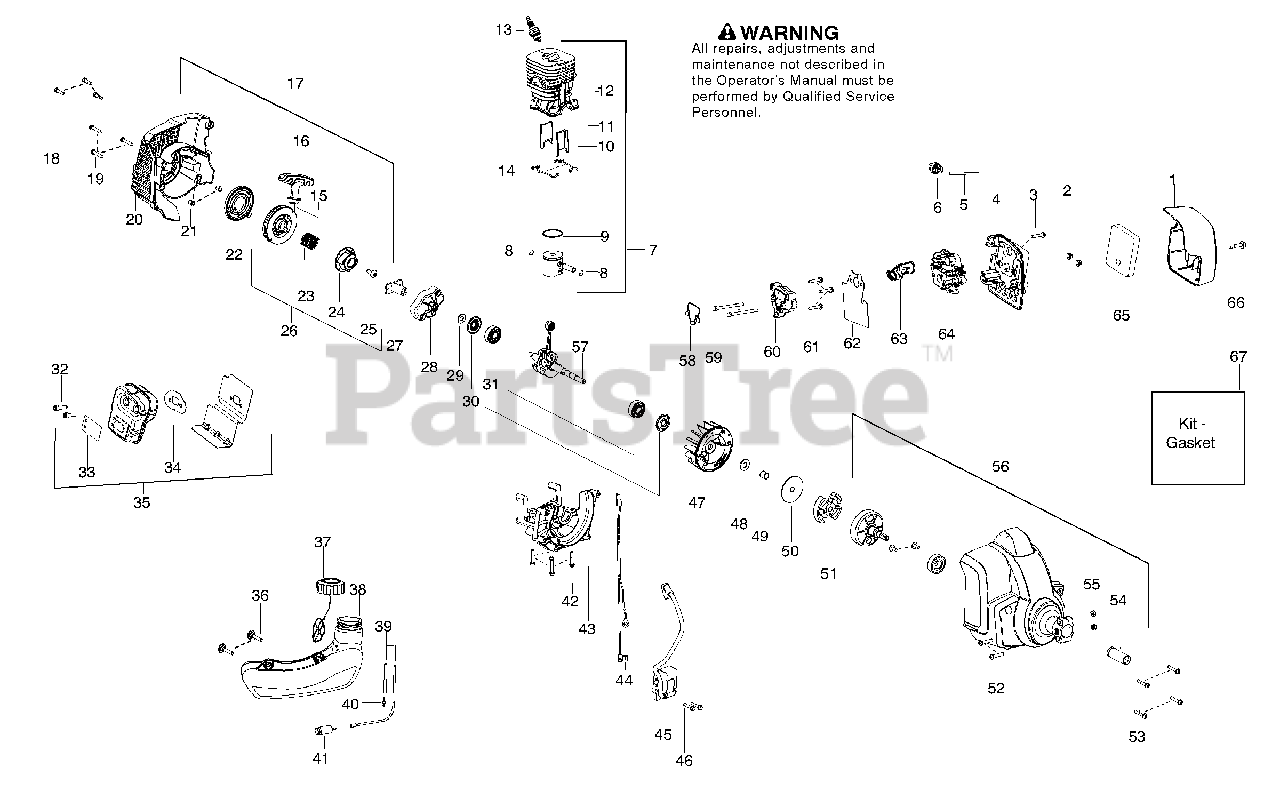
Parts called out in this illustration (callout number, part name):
1	Cover - Airbox
2	Nut - Carb. Screw
4	Base - Airbox
6	Assy - Purge Bulb
7	Kit - Piston/Cylinder
8	Retainer - Piston pin
9	Ring - Piston
10	Insert - Front Transfer Port
11	Insert - Rear Transfer Port
12	Cylinder - Machined
13	Spark Plug (RCJ- 6Y)
14	Seal - Cylinder (Kit)
16	Handle - Starter
17	Assy - Starter/Shroud
18	Screw M4 x 1.75
19	Screw m5x25mm
20	Assy - Starter Hsg. w/eyelet
22	Kit - Starter Spring
23	Spring - Starter Hub
24	Hub - Starter
26	Kit - Starter Pulley
27	Coupling - Starter
28	Assy - Starter Cup
29	Washer - Flat
30	Seal - Crankshaft (kit)
31	Bearing - Crankshaft
32	Bolt - Muffler
33	Kit - Spark Arrestor
34	Gasket - Muffler (kit)
35	Assy - Muffler
36	Screw - Tank Retainer
37	Assy - Fuel Cap w/ret.
38	Assy - Tank
39	Kit - Fuel line
40	Fitting - Fuel Line
41	Assy - Fuel Pickup
42	Screw - m5x25mm
44	Assy - Leadwire
45	Module - Ignition
49	Spacer - Flywheel
50	Washer - Clutch
51	Kit - Clutch Assy.
52	Screw 10-24 x 1"
53	Screw M5 x 25mm
54	Guide - Clutch Drum
55	Locknut 10-24
56	Assy - Fan Housing
57	Kit - Crankshaft Assy.
58	Seal - Cyl./Adapter (kit)
59	Bolt M5 x .80
60	Adaptor - Carburetor
61	Screw .20 x 32
62	Gasket - Carb./Adapter(kit)
64	Kit - Carburetor
67	Kit - Gasket
